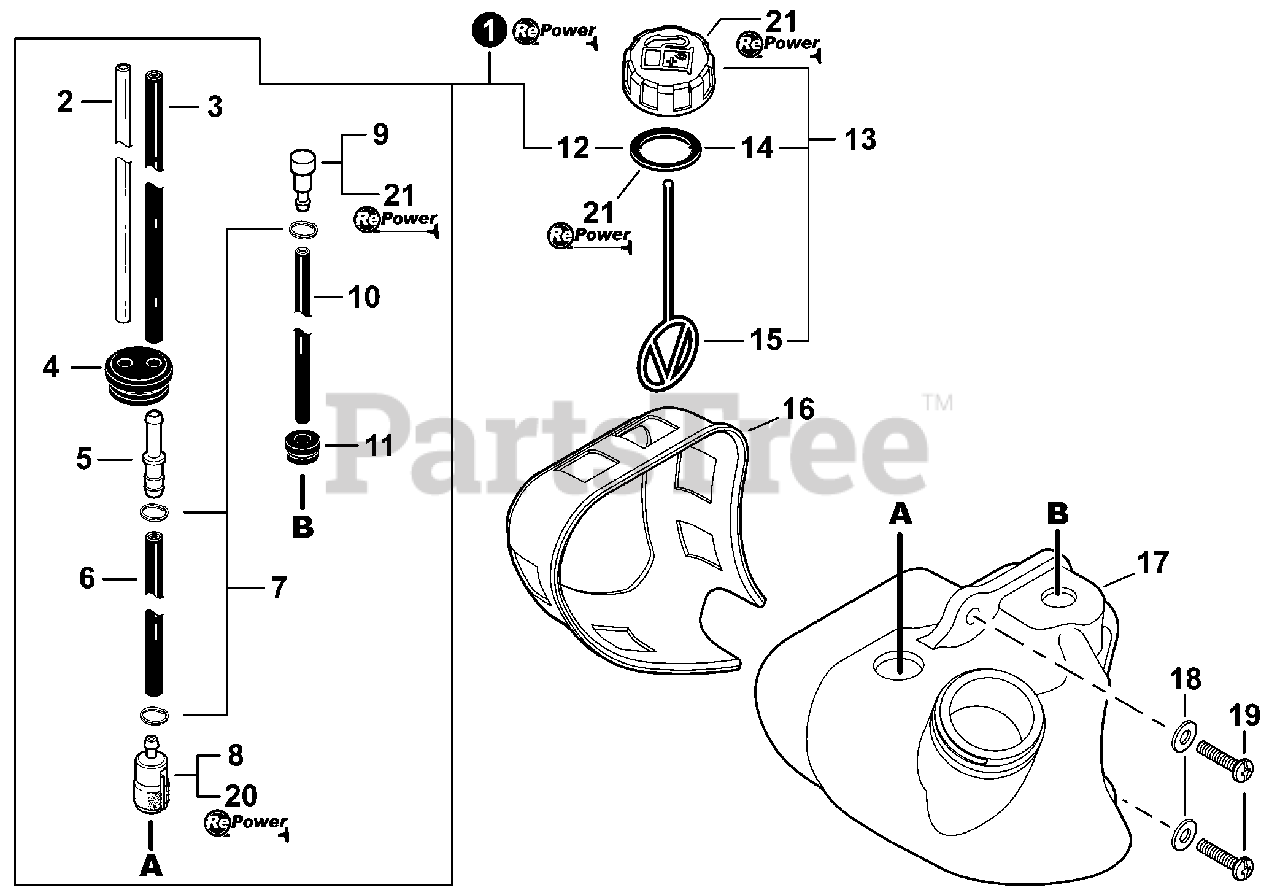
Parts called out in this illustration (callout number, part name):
1	FUEL SYSTEM KIT - REPOWER
2	PIPE, FUEL 3×6×85 CLEAR
3	PIPE, FUEL 3×5×87 BLACK
4	GROMMET, FUEL
5	CONNECTOR, PIPE Ø5ר3.5
6	PIPE, FUEL 3×5×90 BLACK
7	CLIP Ø6
8	FILTER, FUEL
9	VENT ASSY
10	PIPE, FUEL VENT 3×5×50
11	GROMMET
12	GASKET, FUEL CAP
13	CAP ASSY, FUEL
14	GASKET, FUEL CAP
15	CONNECTOR, CAP L= 100mm
16	GUARD, FUEL TANK
17	TANK, FUEL
18	WASHER 5.5×12×0.8
19	SCREW 5×20
20	TUNE-UP KIT - REPOWER
21	CAP/VENT KIT - REPOWER
